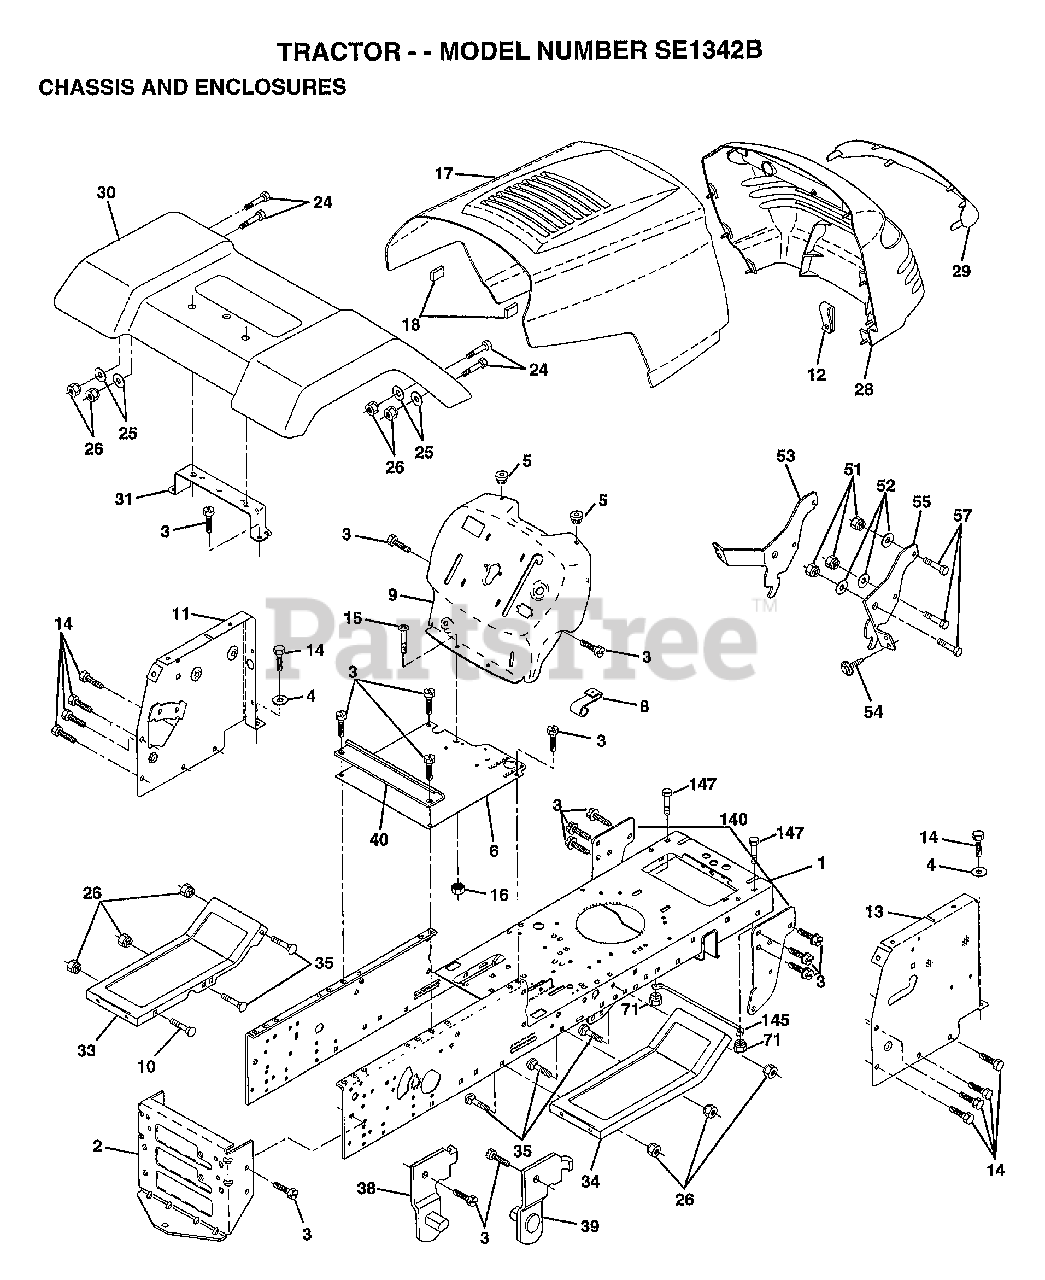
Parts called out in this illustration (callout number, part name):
1	CHASSIS ASM
3	SCREW
4	WASHER
5	BUMPER-HOOD/DASH
6	SADDLE
8	"CLIP,INSULATOR"
9	DASH.SILKSCREENED
11	"PANEL-DASH,LH"
12	CLIP.TINNERMAN
14	SCREW LT
15	SCREW
18	MANUAL
24	BOLT
25	WASHER
26	NUT
28	GRILLE-MS428
29	LENS GRILLE
30	FENDER LT
31	BRACKET SUPT FEND
33	FOOTREST LH
34	FOOTREST RH
35	BOLT
38	BRACKET ASM LH
39	BRACKET ASM RH
40	SPACER FENDER LT
51	NUT
52	WASHER
53	BRACKET.GRILLE.LH
54	SCREW SPIDERLK #8 X 7/8
55	BRACKET.GRILLE.RH
140	BRKT SUSPENSION
145	"ROD POVOT,CHASSIS"
147	BOLT LT
